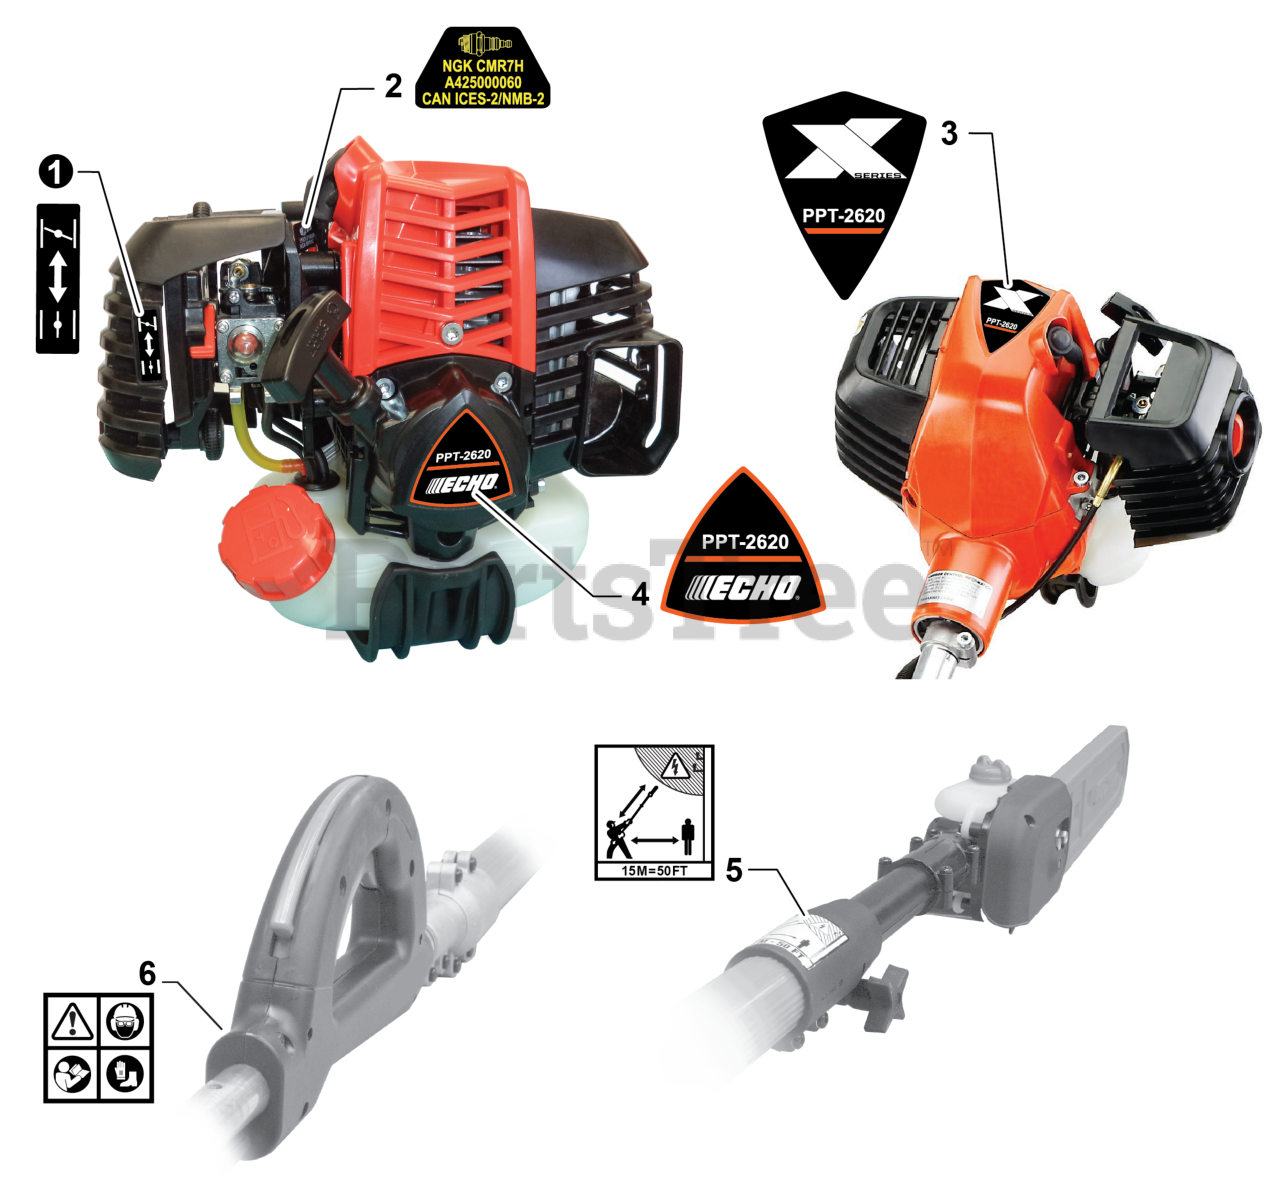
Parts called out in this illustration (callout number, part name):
1	LABEL - CHOKE
2	LABEL - SPARK PLUG - CMR7H
3	LABEL - MODEL PPT-2620
4	LABEL - RECOIL STARTER - PPT-2620
5	LABEL - CAUTION
6	LABEL - CAUTION
